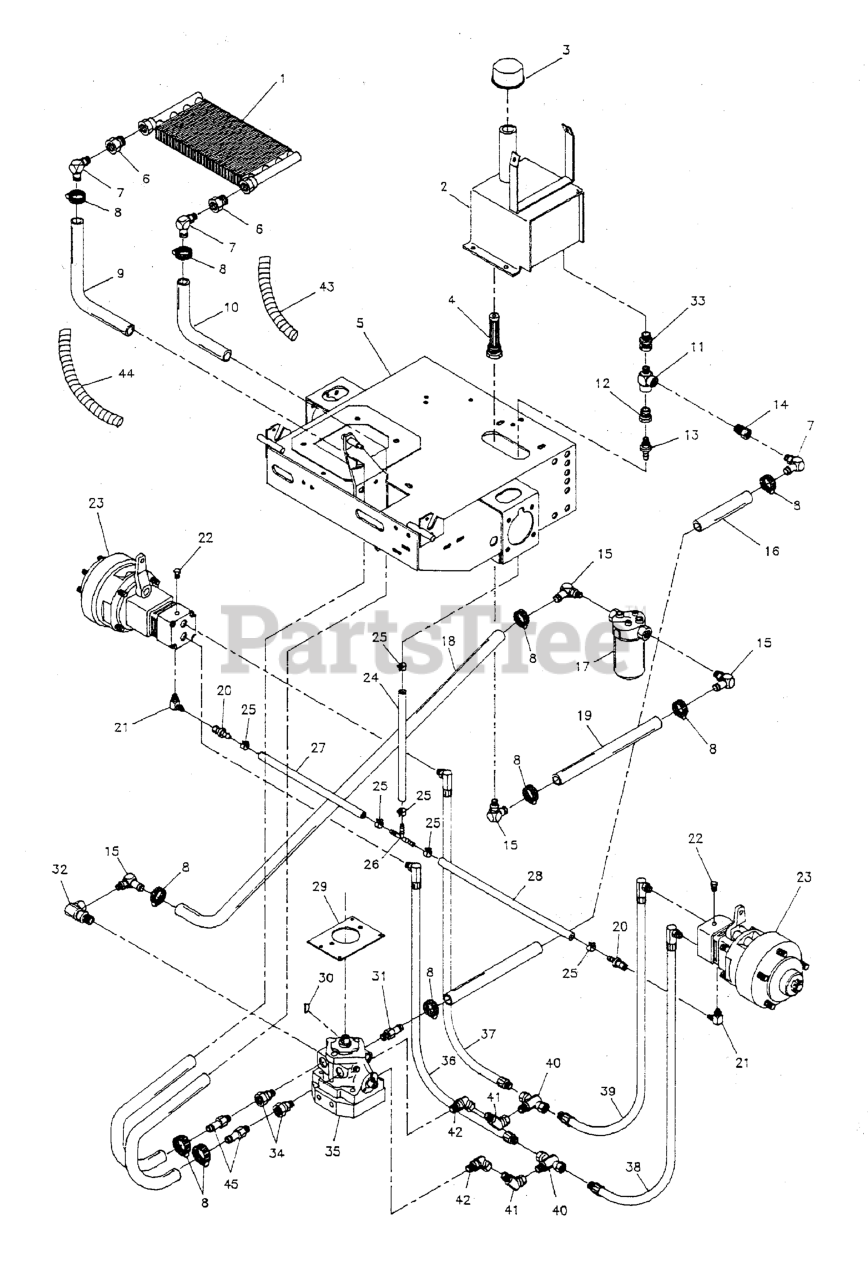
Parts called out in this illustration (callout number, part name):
1	OIL COOLER
2	HYDRO TANK WELDMENT
3	BREATHER
4	STRAINER
5	ENGINE DECK
6	FITTING, Reducer
7	FITTING, NPT - Hose, 90 Deg.
8	CLAMP, #6 Hose
9	HOSE, 39" Long
10	HOSE, 29"
11	FITTING, Tee
12	FITTING, Reducer
13	FITTING, Male Adapter
14	FITTING, Reducer
15	FITTING, 1/2" NPT, 90 Deg.
16	HOSE, 10-1/2"
17	FILTER HEAD
18	HOSE, 9-3/4"
19	HOSE, Hydraulic, 22-3/4"
20	FITTING, Male Adapter
21	FITTING, 7/16" O-Ring 90 Degree Swivel
22	FITTING, Plug
23	HYDRAULIC WHEEL MOTOR
24	HOSE, 3" Long
25	CLAMP, Hose
26	FITTING, Tee
27	HOSE, 5-1/4"
28	HOSE, 25"
29	PLATE, Pump Mount
30	KEY, #61 Woodruff
31	FITTING, O-Ring - Hose
32	FITTING, O-Ring, 90 Deg.
33	FITTING, Straight Swivel
34	FITTING, O-Ring - NPT, Swivel
35	HYDRAULIC PUMP
36	HOSE ASSEMBLY, 17"
37	HOSE ASSEMBLY, 19"
38	HOSE ASSEMBLY, 15"
39	HOSE ASSEMBLY, 13"
40	FITTING, Tee
41	FITTING, 1/2 NPT, 45 Deg. Swivel
42	FITTING, O-Ring - NPT, 45 Deg.
43	WIRE LOOM, 26"
44	WIRE LOOM, 38"
45	FITTING, 3/8NPT-1/2" Hose, Straight
